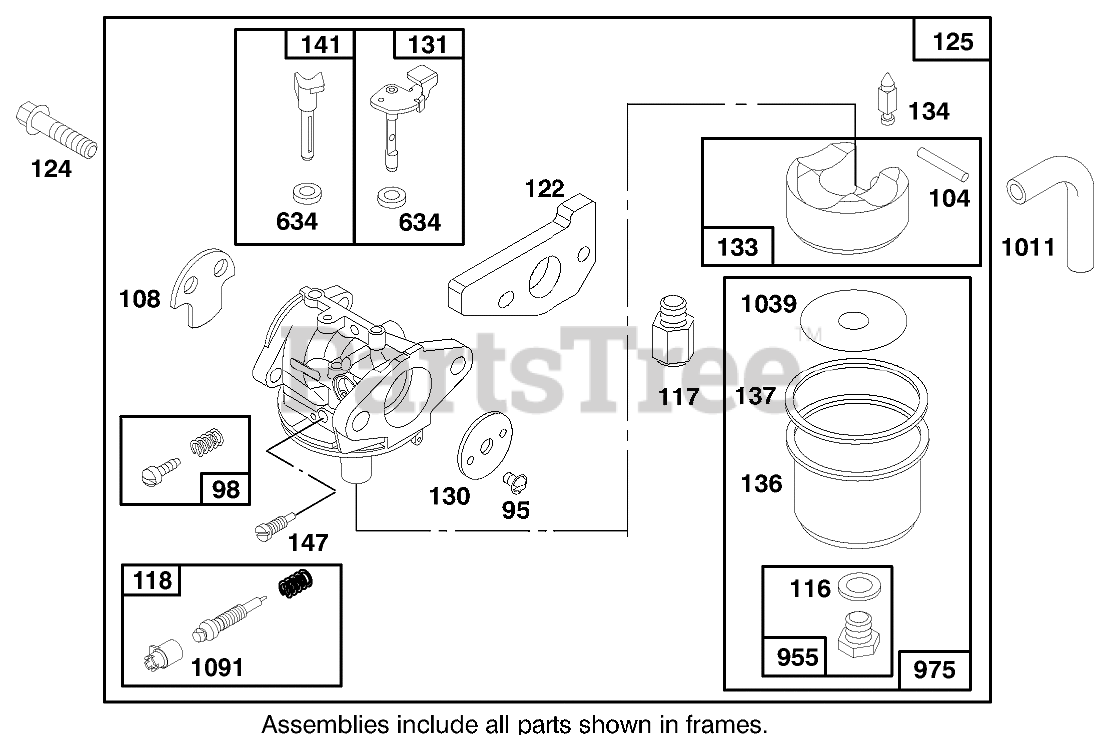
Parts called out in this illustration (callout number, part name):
95	SCREW - ROUND HEAD
98	IDLE ADJUSTING SCREW
104	FLOAT HINGE PIN
108	VALVE - CHOKE
116	SEALING GASKET
117	Jet-Main
118	VALVE/SPRING - NEEDLE
122	ADAPTER ASSEMBLY
124	HEX HEAD SCREW
125	ASSEMBLY - CARBURETOR
130	THROTTLE VALVE
131	THROTTLE SHAFT
133	FLOAT-CARBURETOR
134	Valve-Inlet (Includes Seat)
136	FLOAT BOWL
137	FLOAT BOWL GASKET
141	CHOKE SHAFT
147	JET - PILOT
634	SEAL WASHER
955	HEX HEAD SCREW
975	CARBURETOR BOWL ASM
1011	VENT TUBE
1039	FLOAT LIMITER
1091	CAP - LIMITER
